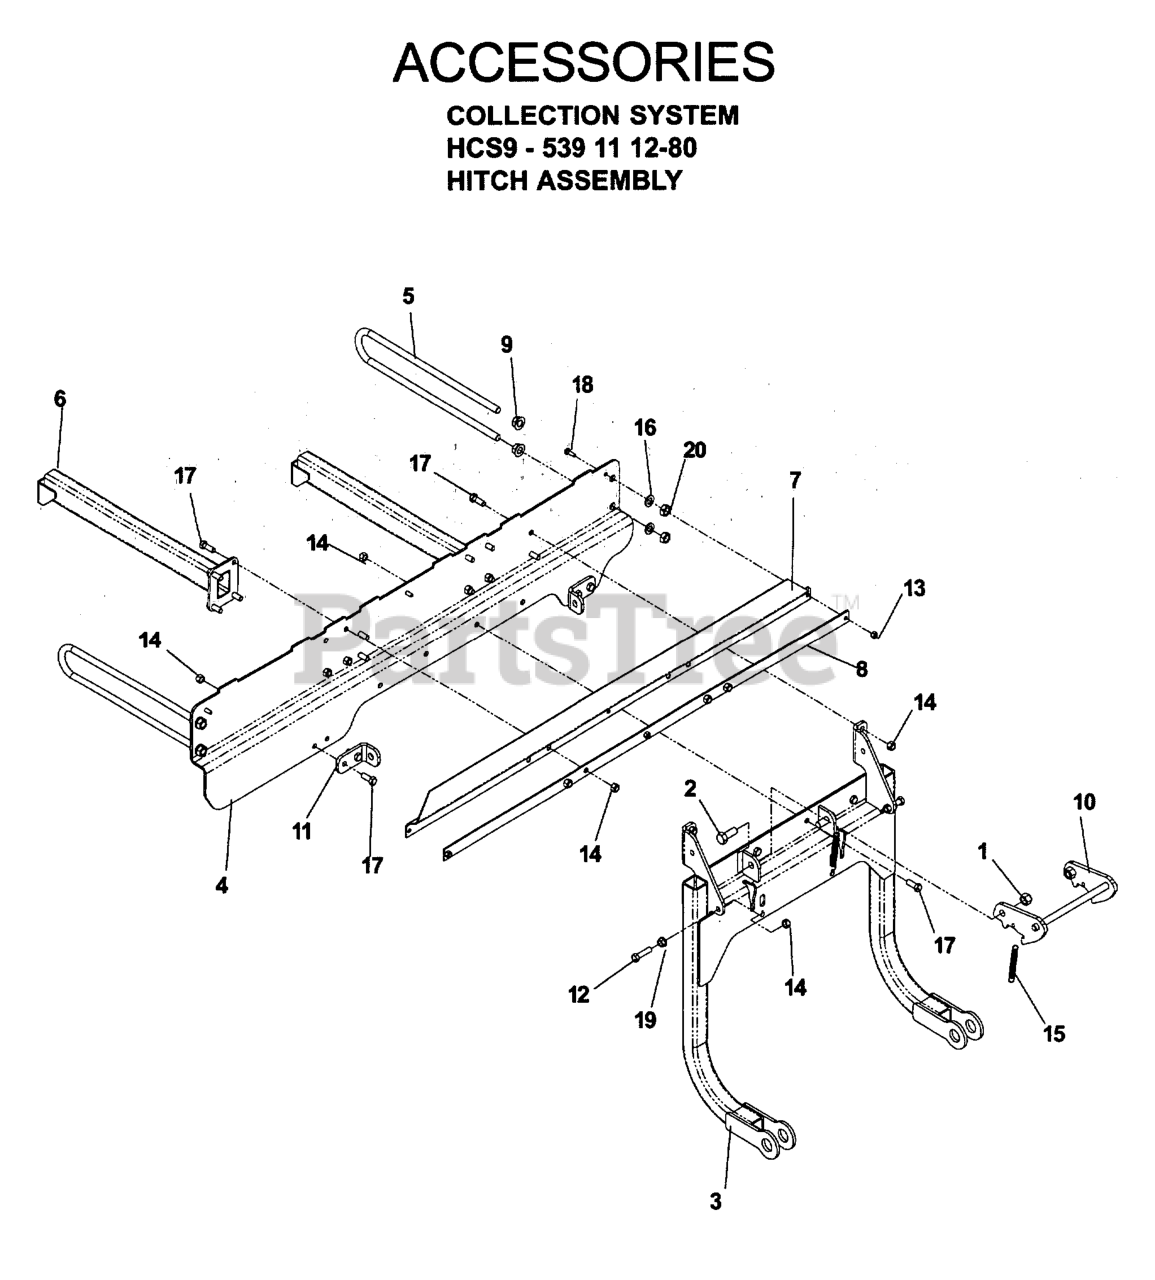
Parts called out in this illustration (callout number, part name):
1	NUT 1/2-13 HEX NYLOC ZD
2	HCS 1/2-13 X 1-1/4
3	HITCH WELDMENT
4	MOUNT Z BRACE
5	SUPPORT, OUTER
6	SUPPORT ARM WELDMENT
7	SEAL, RUBBER
8	SEAL STRAP
9	NUT 1/2-13 HEX
10	LATCH WELDMENT
11	BRACKET, SUPPORT
12	HCS 3/8C X 1 1/2
13	NUT.1/4-20.HEX.NYLOC.ZD
14	NUT 3/8-16 NYLOC
16	WASHER 1/2" SPLIT LOCK
17	HCS 3/8-16X1.GRD.5.ZD
18	HCS 1/4C X 3/4 HCS
19	NUT 3/8C WHIZ
20	NUT 1/2 HEX JAM
